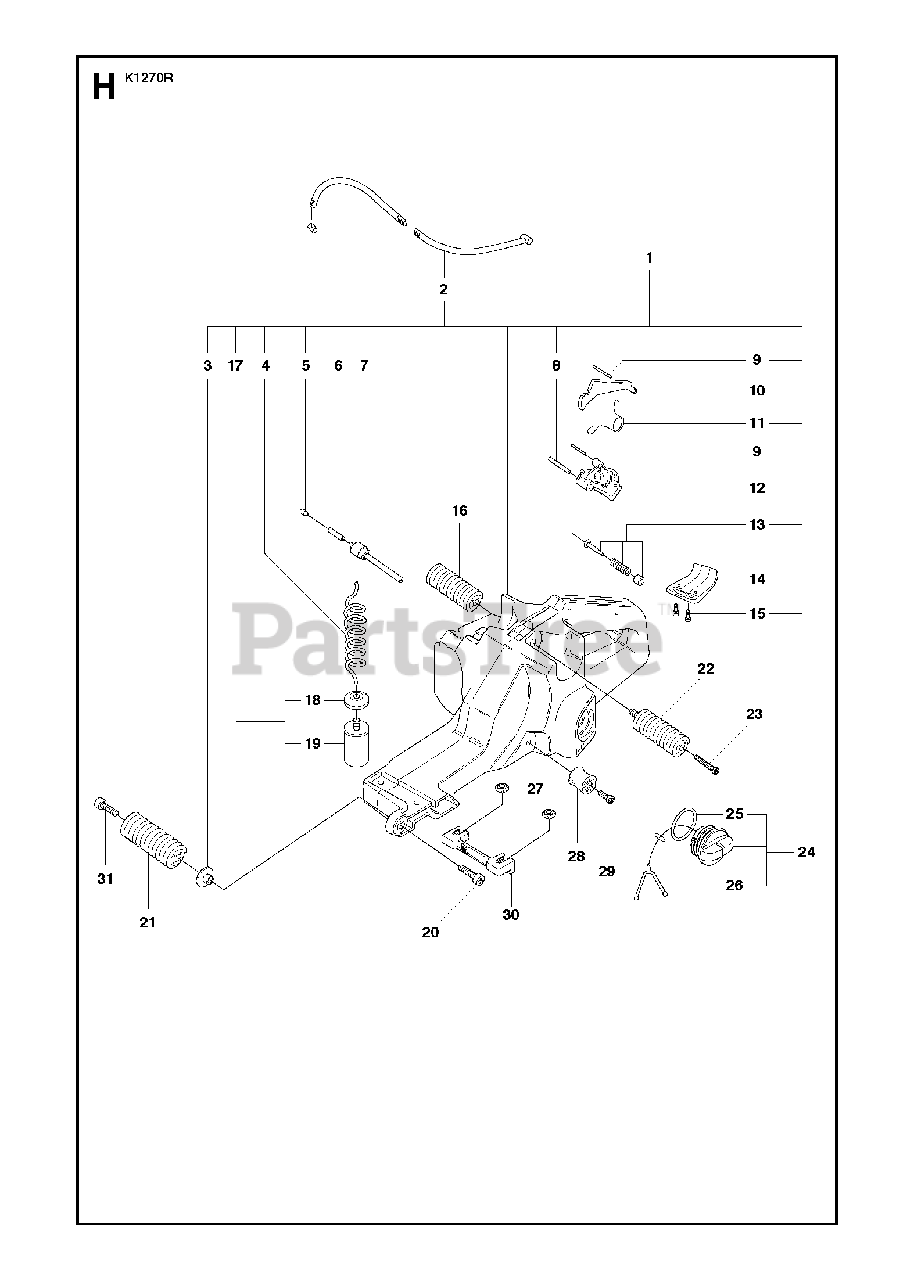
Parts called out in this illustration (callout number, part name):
1	FUEL TANKIncl. 1 - 15, 17
4	FUEL HOSE
7	TANK VENT
8	PARALLEL PIN
9	PARALLEL PIN
10	THROTTLE LOCKOUT
12	THROTTLE CONTROL ASSY
13	SPÄRRSTIFT RES
15	SCREW CRCSFT
16	ANTIVIBRATION ELEMENT
17	FUEL FILTERIncl. 18 - 19
20	SCREW ITXSCM
21	ANTIVIBRATION ELEMENT
22	ANTIVIBRATION ELEMENT
23	SCREW ITXSCM
24	TANK CAP ASSYIncl. 25 - 26
27	NUT
28	ANTIVIBRATION ELEMENT
29	SCREW ITXSCM
31	SCREW ITXSCM
